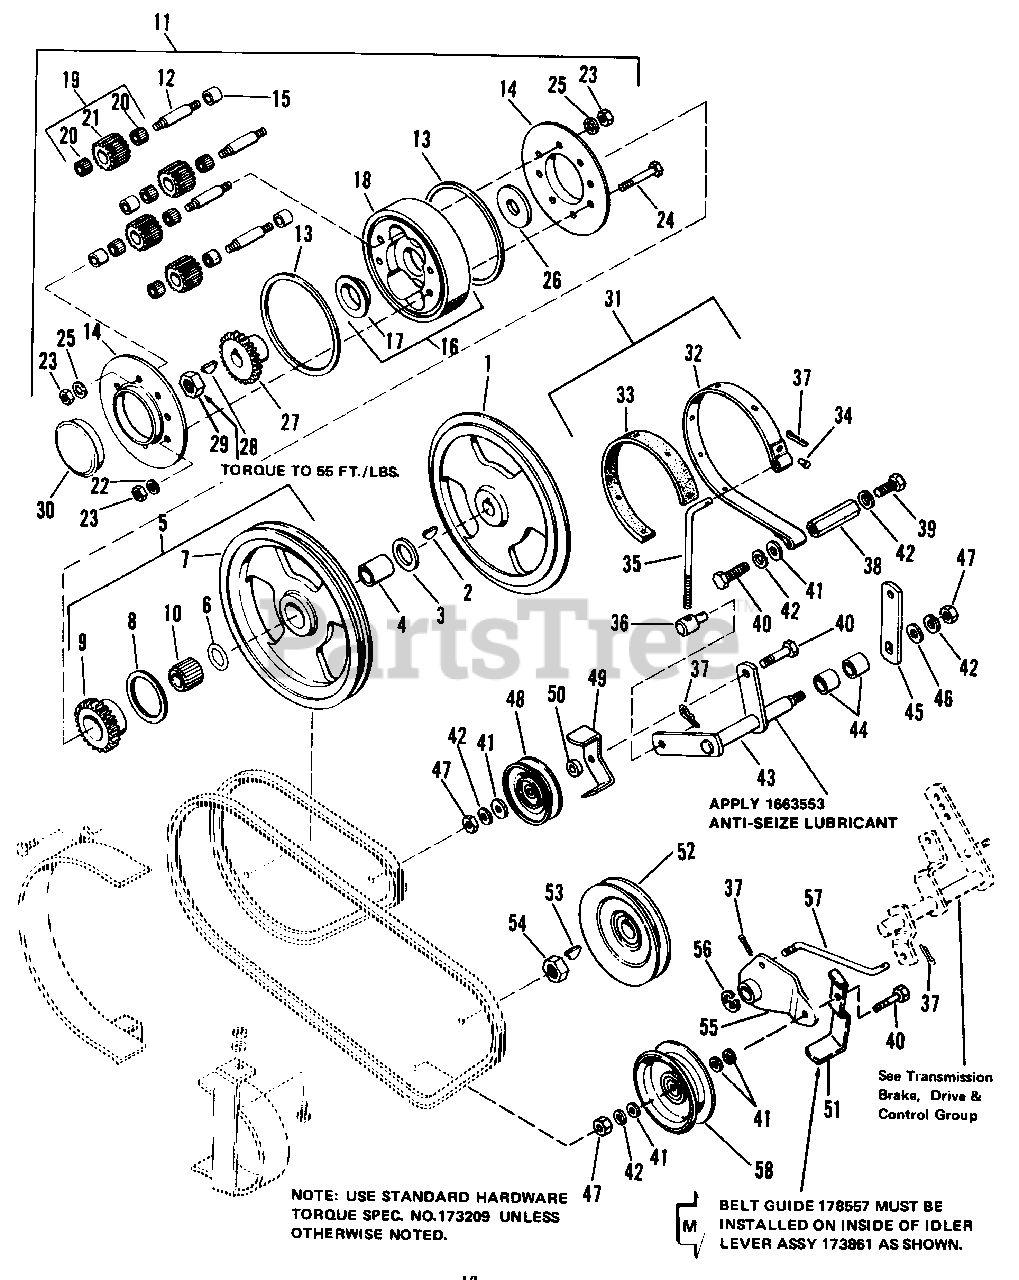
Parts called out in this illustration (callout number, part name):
1	PULLEY, Half
2	KEY, Woodruff, No. 9
3	BEARING, Thrust
4	RACE, Inner
5	PULLEY ASSY
9	GEAR, Sun
10	BEARING, Needle
11	PLANETARY ASSY
12	PIN, Pinion
14	COVER, Differential
15	BEARING, Sleave
16	CARRIER SUB- ASSY, Planetary
17	BEARING, Flange
18	CARRIER, Planetary
19	PINION ASSY, Planetary
20	BEARING, Needle
21	PINION, Planetary
22	LOCKWASHER, 5/16
23	NUT, Hex, Full, 5/16-18
24	CAPSCREW, Hex Hd., 5/16-18 x 2
25	LOCKWASHER, Internal, 5/16
26	WASHER, Thrust
27	GEAR, Sun
28	KEY, Woodruff, No. 9
29	NUT, Hex, Jam, Lock, 3/4-16
31	BRAKE BAND ASSY
32	BAND, Brake
34	RIVET, No. 7 x 1/4
37	PIN, Cotter, 3/32 x 3/4
38	ANCHOR, Brake
39	CAPSCREW, Hex Hd., 3/8-16 x 1
40	CAPSCREW, Hex Hd., 3/8-16 x 1-1/2
41	WASHER, 5/16
42	LOCKWASHER, 3/8
43	LEVER ASSY
46	WASHER, 3/8
47	NUT, Hex, Full, 3/8-16
49	GUIDE, Belt
51	GUIDE, Belt
54	NUT, Hex, Jam, Lock, 3/4-16
55	LEVER ASSY, Idler
56	"E" RING
57	LINK, Clutch
58	PULLEY
